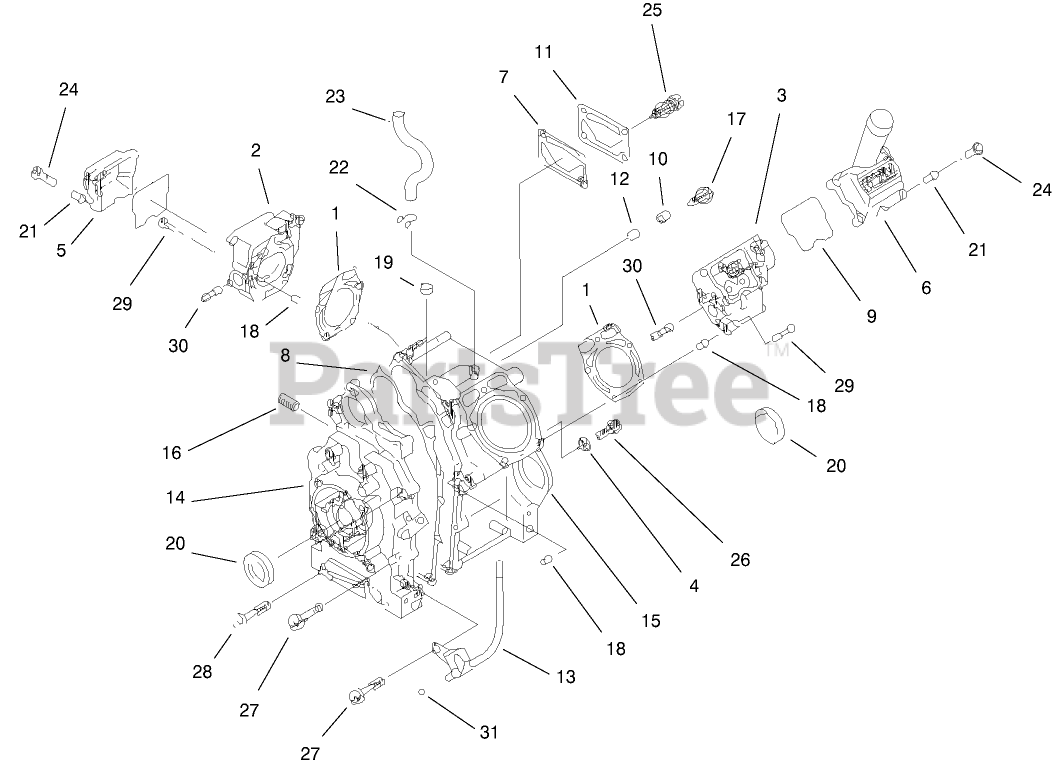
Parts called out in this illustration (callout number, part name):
1	GASKET HEAD
3	HEAD CYL
4	GASKET
5	CASE-ROCKER
7	GASKET
9	GASKET-ROCKERCASE
11	COVER
12	VALVE
13	PIPE - OIL LEVEL
14	COVER-CRANKCASE
16	JOINT
17	SCREW
19	SEAL-OIL, VC (6X10X2.5)
20	SEAL-OIL
21	COLLAR
25	BOLT-FLANGED
26	BOLT-FLANGED
29	BOLT-FLANGED
30	BOLT-STUD
31	O-RING
